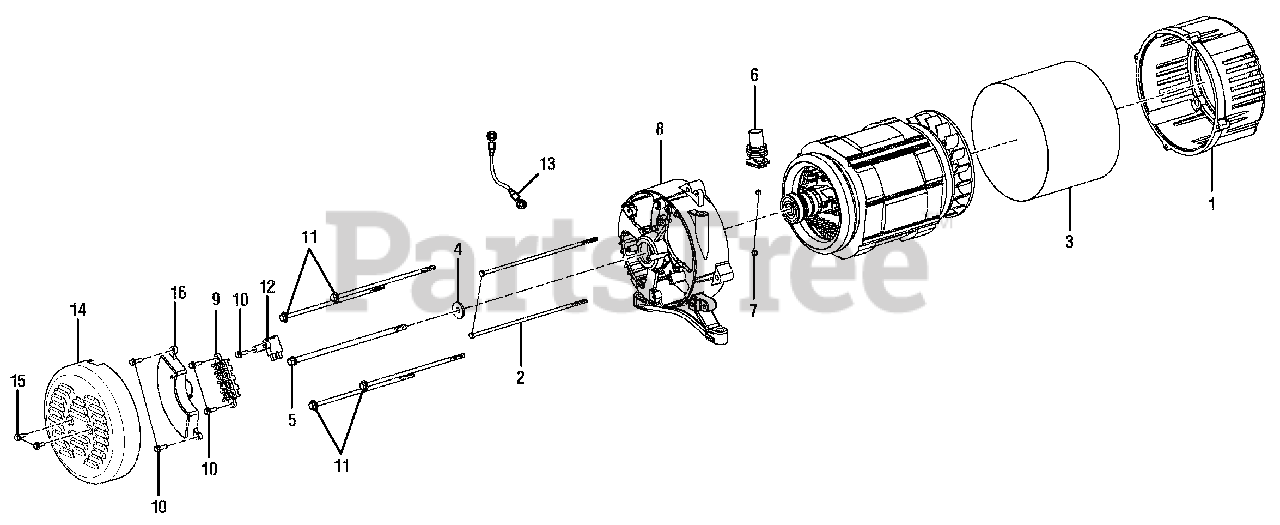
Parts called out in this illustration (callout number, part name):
1	Adaptor Housing
2	Bolt (M5, Hex Hd.)
3	Generator Head Cover
4	Lock Washer (5/16 in.)
5	Rotor Bolt (170 mm)
6	Rubber Boot
7	Hex Nut (M5)
8	Bearing Housing
9	Terminal Block
10	Bolt (M5 x 16 mm)
11	Stator Bolt (170 mm)
12	Brush Assembly
13	Bonding Wire
14	Brush Cover
15	Bolt (M5 x 12 mm)
16	Automatic Voltage Regulator
